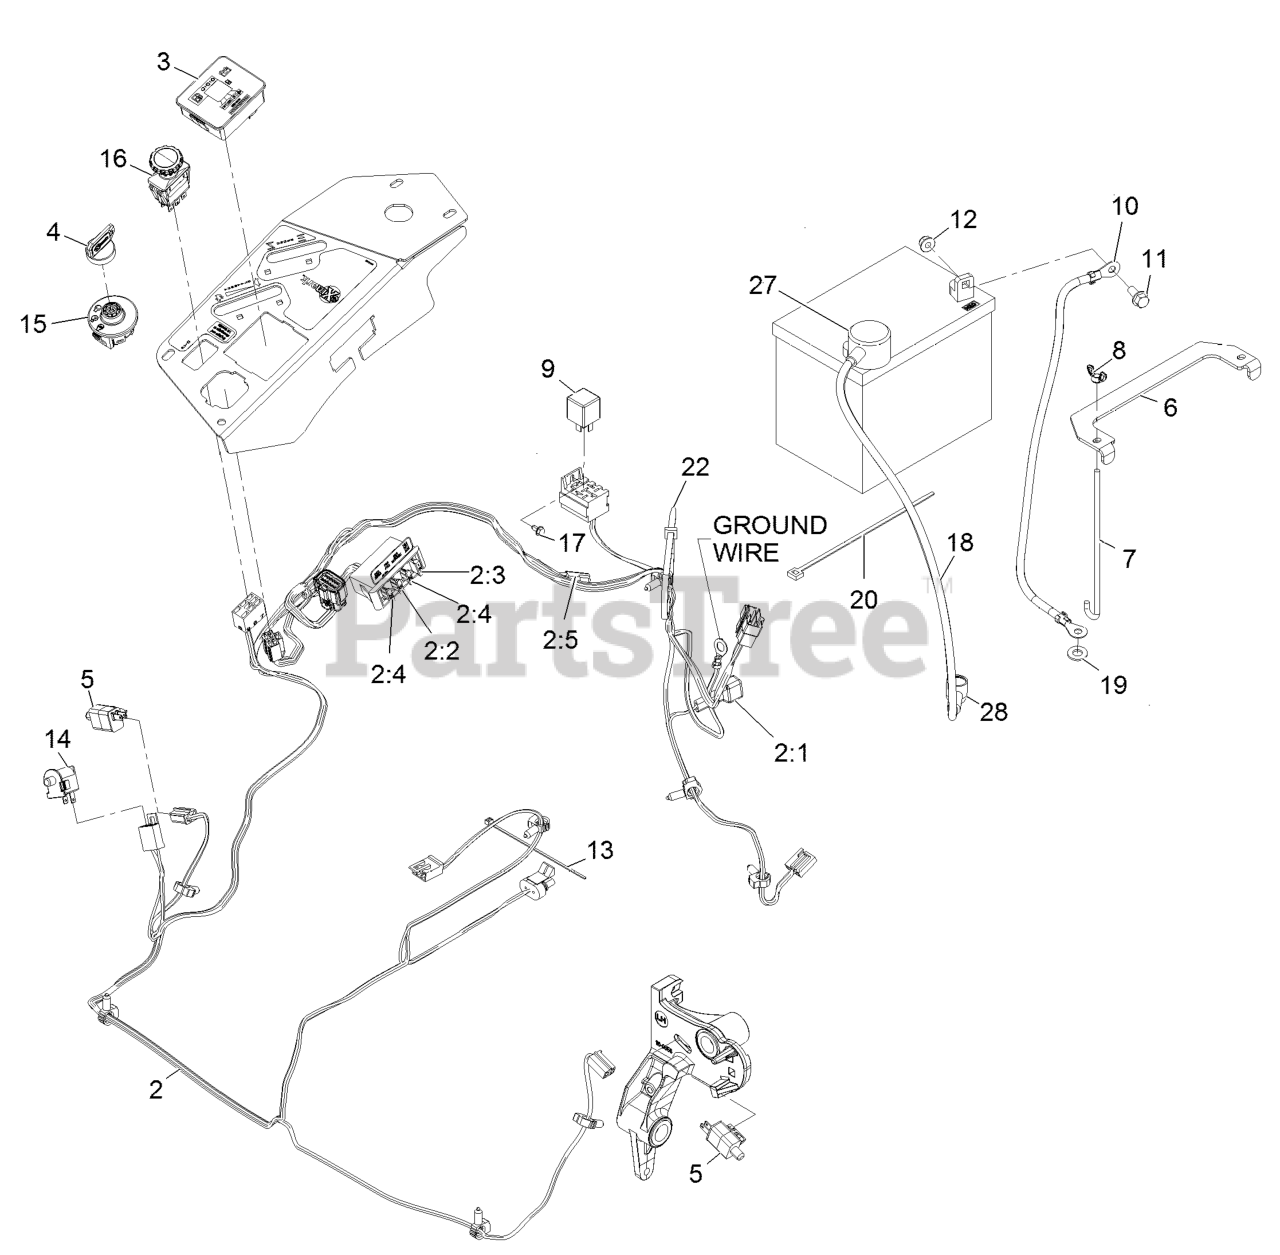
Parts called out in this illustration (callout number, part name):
2	HARNESS-WIRE, MAIN
2:2	FUSE-BLADE, 10 AMP
2:3	FUSE-BLADE, 15 AMP
2:4	FUSE-BLADE, 25 AMP
2:5	CAP-PLUG
3	FUEL/HOUR METER ASM
4	KEYS-IGNITION (SPARE PAIR
4	KEY-IGNITION
6	STRAP-TIE DOWN, BATTERY
7	BOLT-HOLDDOWN
8	WINGNUT
10	CABLE-BATTERY, NEGATIVE
11	SCREW-HHF
12	NUT-HF, NI
13	TIE-CABLE
14	SWITCH-BAIL
16	SWITCH-PTO, 10 AMP
17	SCREW-HWH
18	CABLE-BATTERY, POSITIVE
19	WASHER-FLAT
20	TIE-PLASTIC
22	TIE-PLASTIC
27	INSULATOR-BATTERY
28	INSULATOR-SOLENOID
